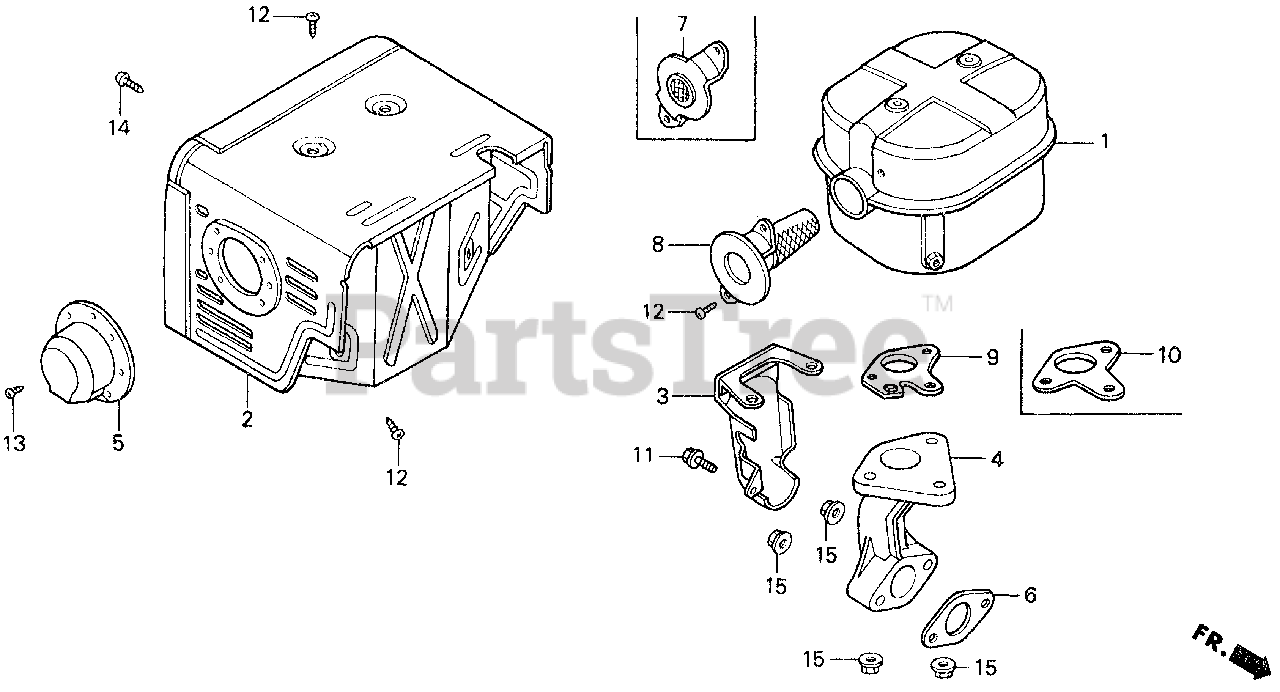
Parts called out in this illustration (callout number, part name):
1	MUFFLER
2	PROTECTOR, MUFFLER
3	PROTECTOR, EX. PIPE
4	PIPE, EX.
6	GASKET, EX. PIPE
6	GASKET, EX. PIPE (WACKER)
8	ARRESTER, SPARK
9	GASKET, MUFFLER (ARRESTER)
11	BOLT, FLANGE (6X12) (CT200)
12	SCREW, TAPPING (5X8)
14	SCREW, PAN (6X6)
15	NUT, FLANGE (8MM)
